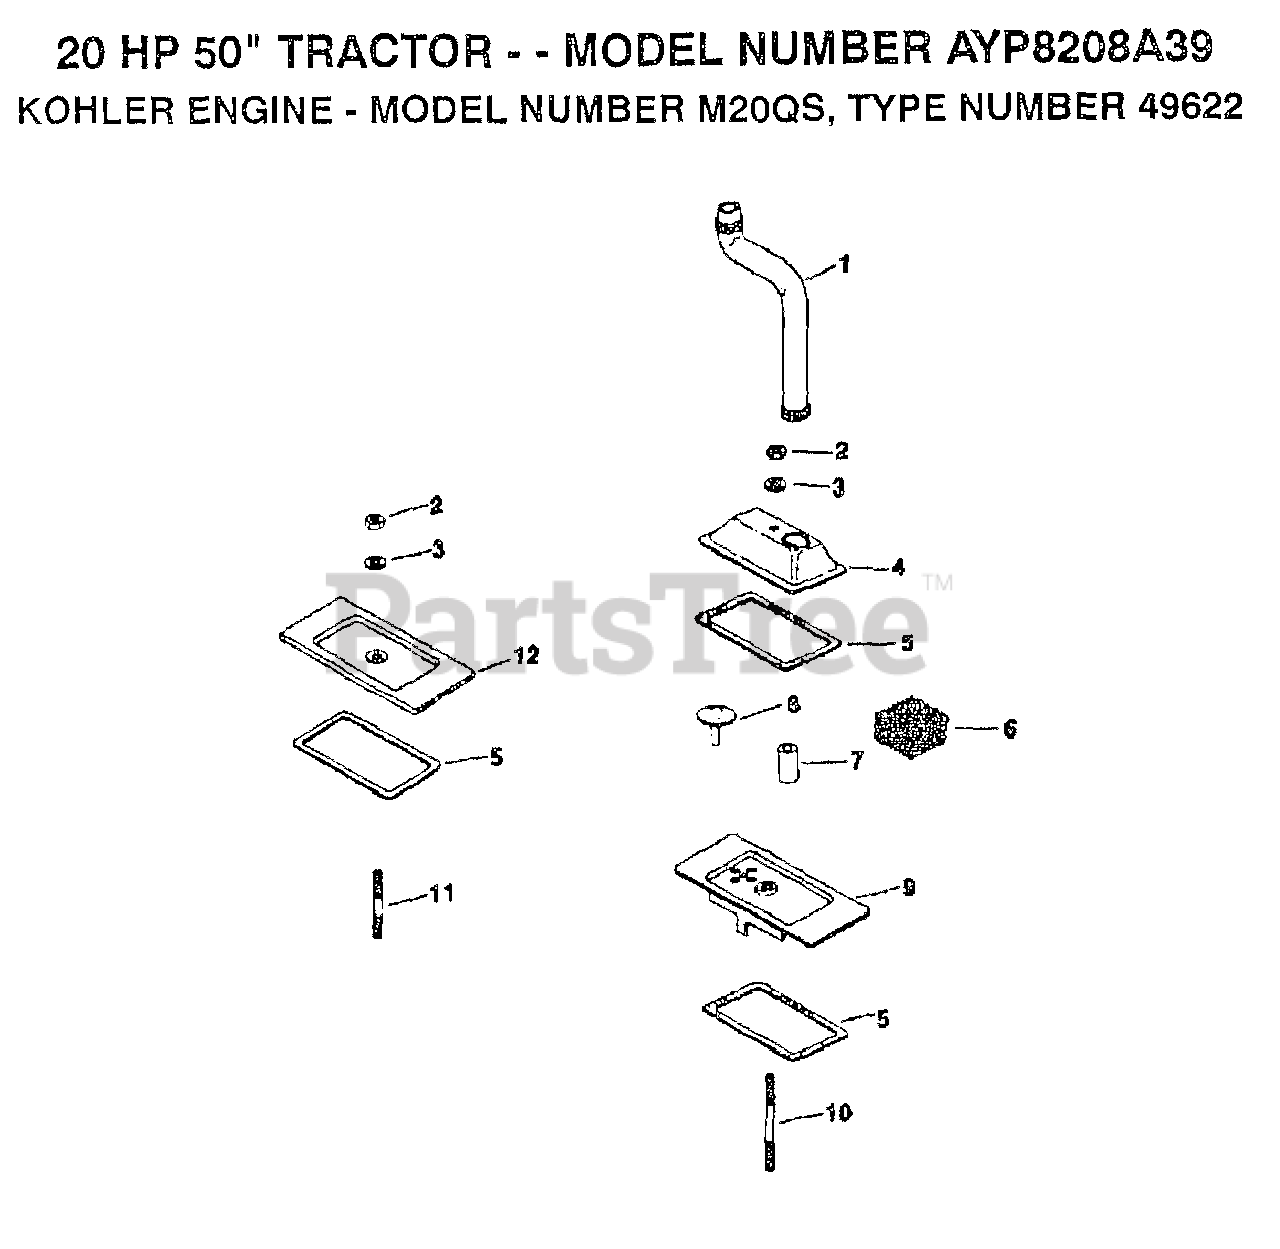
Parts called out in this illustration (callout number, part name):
1	HOSE, BREATHER
2	NUT
3	WASHER
4	COVER, #1 UPPER CYLINDER VALVE
6	FILTER, BREATHER
7	SEAL, BREATHER
8	VALVE, BREATHER
9	COVER, #1 LOWER CYLINDER VALVE
10	STUD
11	STUD
12	COVER, #2 CYLINDER VALVE
